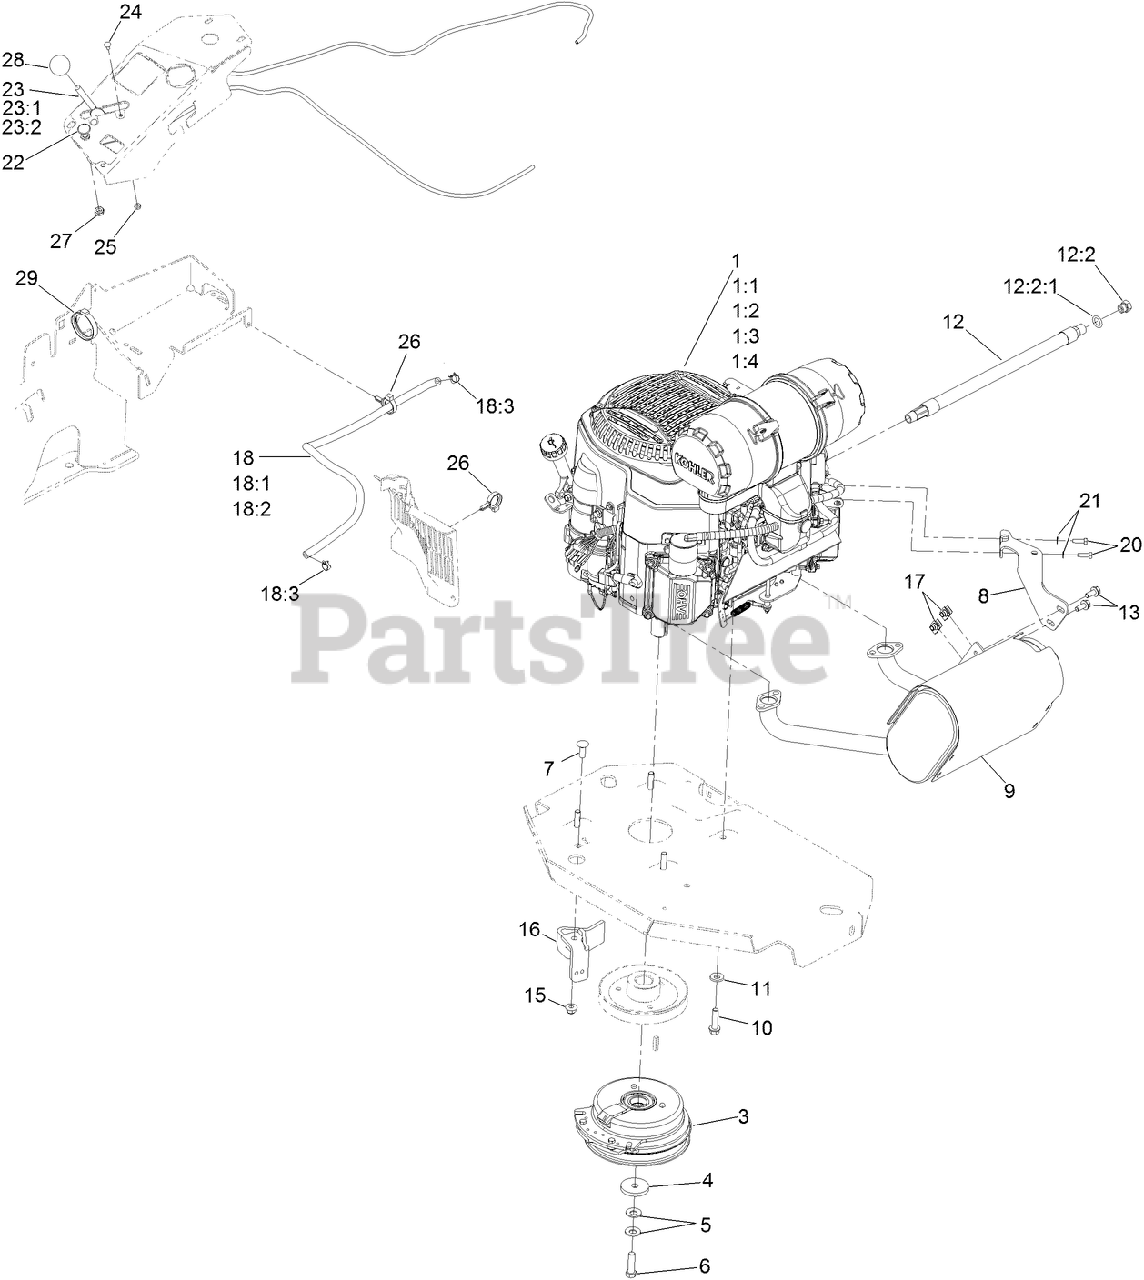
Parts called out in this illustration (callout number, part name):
1:1	KOHLER 52 050 02-S ENGINE OIL FILTER
1:2	KOHLER 25 083 01-S ENGINE AIR FILTER
1:3	KOHLER 25 083 04-S SAFETY FILTER
1:4	KOHLER 24 050 13-S FUEL FILTER
3	CLUTCH KIT
4	WASHER-CLUTCH
5	WASHER-SPRING
6	SCREW-HH, W/LOCTITE
7	SCREW-CARR
8	MUFFLER BRACKET KIT
9	MUFFLER KIT
10	SCREW-HWH
11	WASHER-BELLEVILLE
12	OIL DRAIN HOSE ASM
12:2	PLUG-HH
12:2:1	O-RING
13	SCREW-HHF
15	NUT-HF, NI
16	CLUTCH-ANCHOR
17	NUT-U
18	FUEL LINE ASM
18:1	HOSE-FUEL
18:2	SLEEVE-THERMAL
18:3	CLAMP-HOSE
20	SCREW-HH
21	WASHER-SPRING
22	CHOKE CONTROL ASM
23	THROTTLE CONTROL ASM
23:1	LEVER-THROTTLE
24	BOLT-CARR
25	NUT-LOCK, NI
26	CLAMP-HOSE
27	NUT-HJ
28	KNOB-BALL
29	CLAMP-HARNESS
